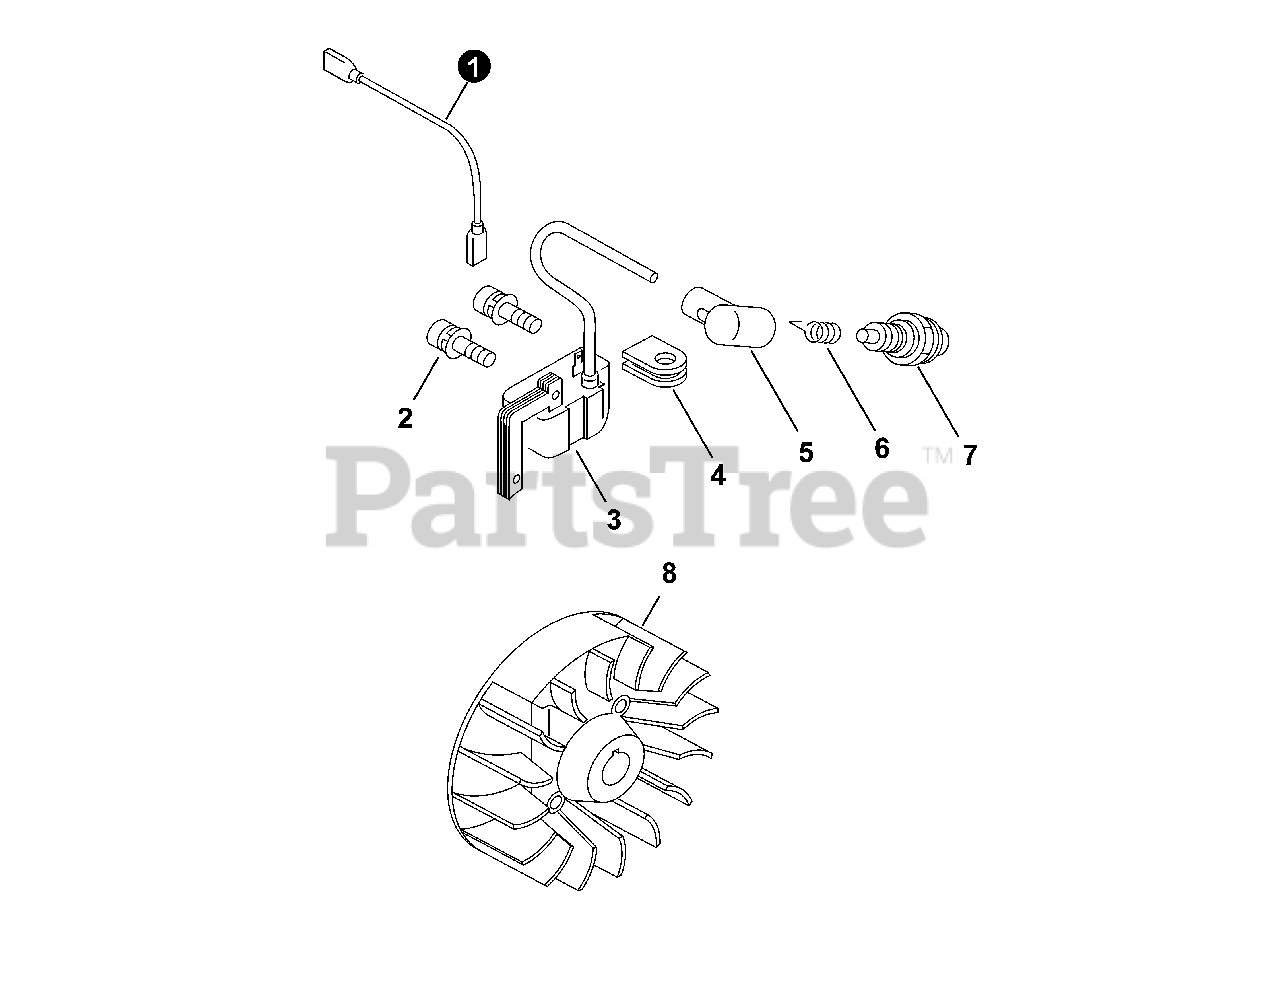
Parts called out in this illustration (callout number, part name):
1	LEAD
2	SCREW 4x22
3	COIL, IGNITION
5	CAP, SPARK PLUG
6	TERMINAL, SPARK PLUG
7	SPARK PLUG - BPM7A
8	FLYWHEEL
